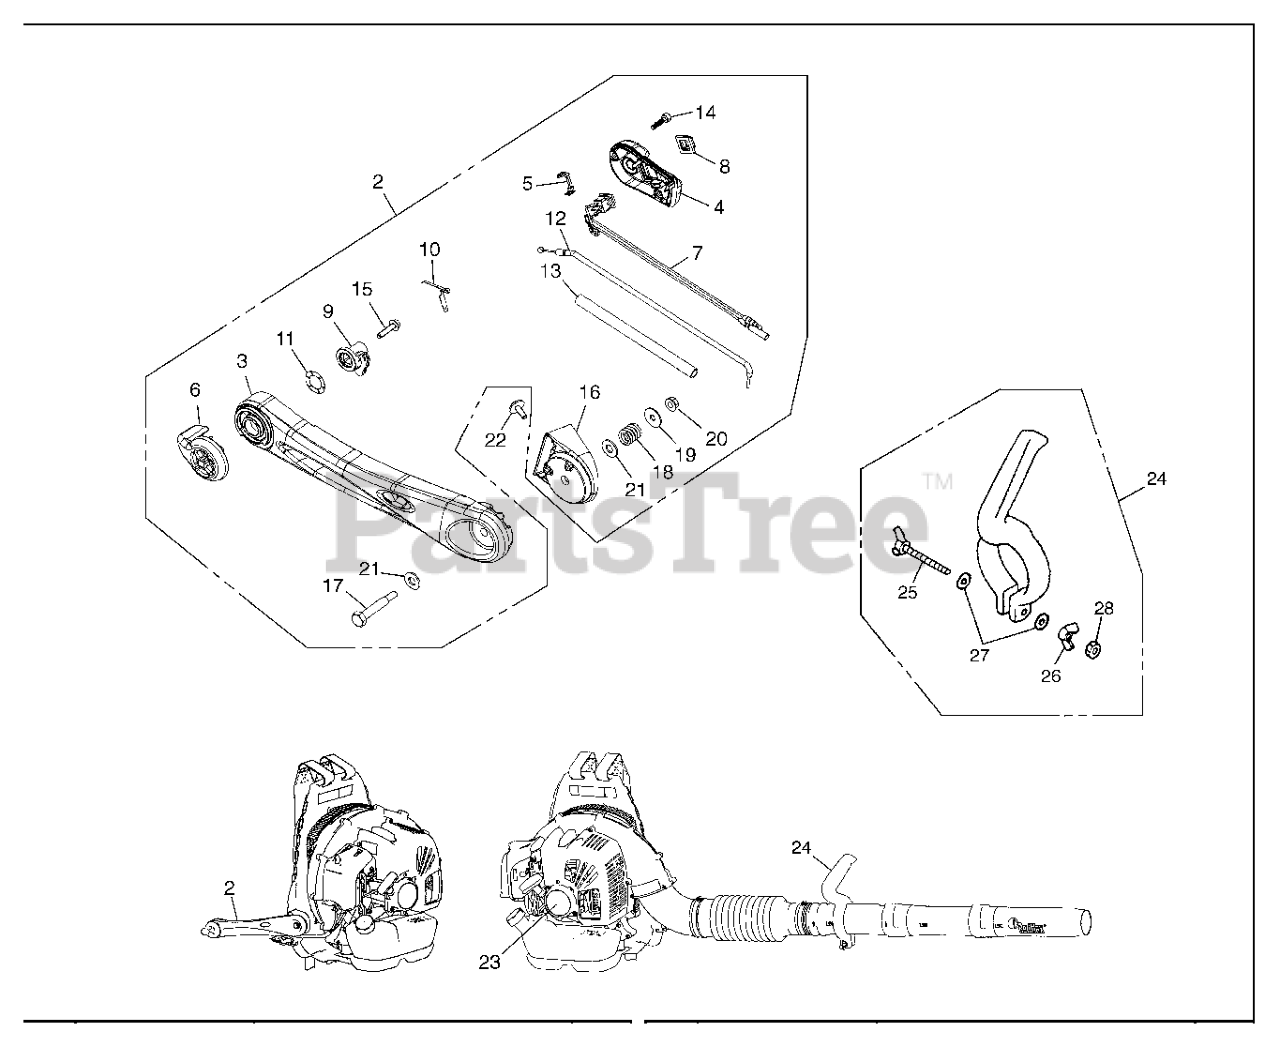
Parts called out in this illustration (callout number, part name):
2	LEVER,SET
6	LEVER,THROTTLE
8	CAP SWITCH
10	PLATE, CONTACT
11	WASHER WAVE
15	BOLT
19	WASHER Z349525440
20	NUT 8488646000
23	RECOIL DECAL
24	GRIP ASSY
25	WING BOLT
26	WING NUT
27	WASHER
